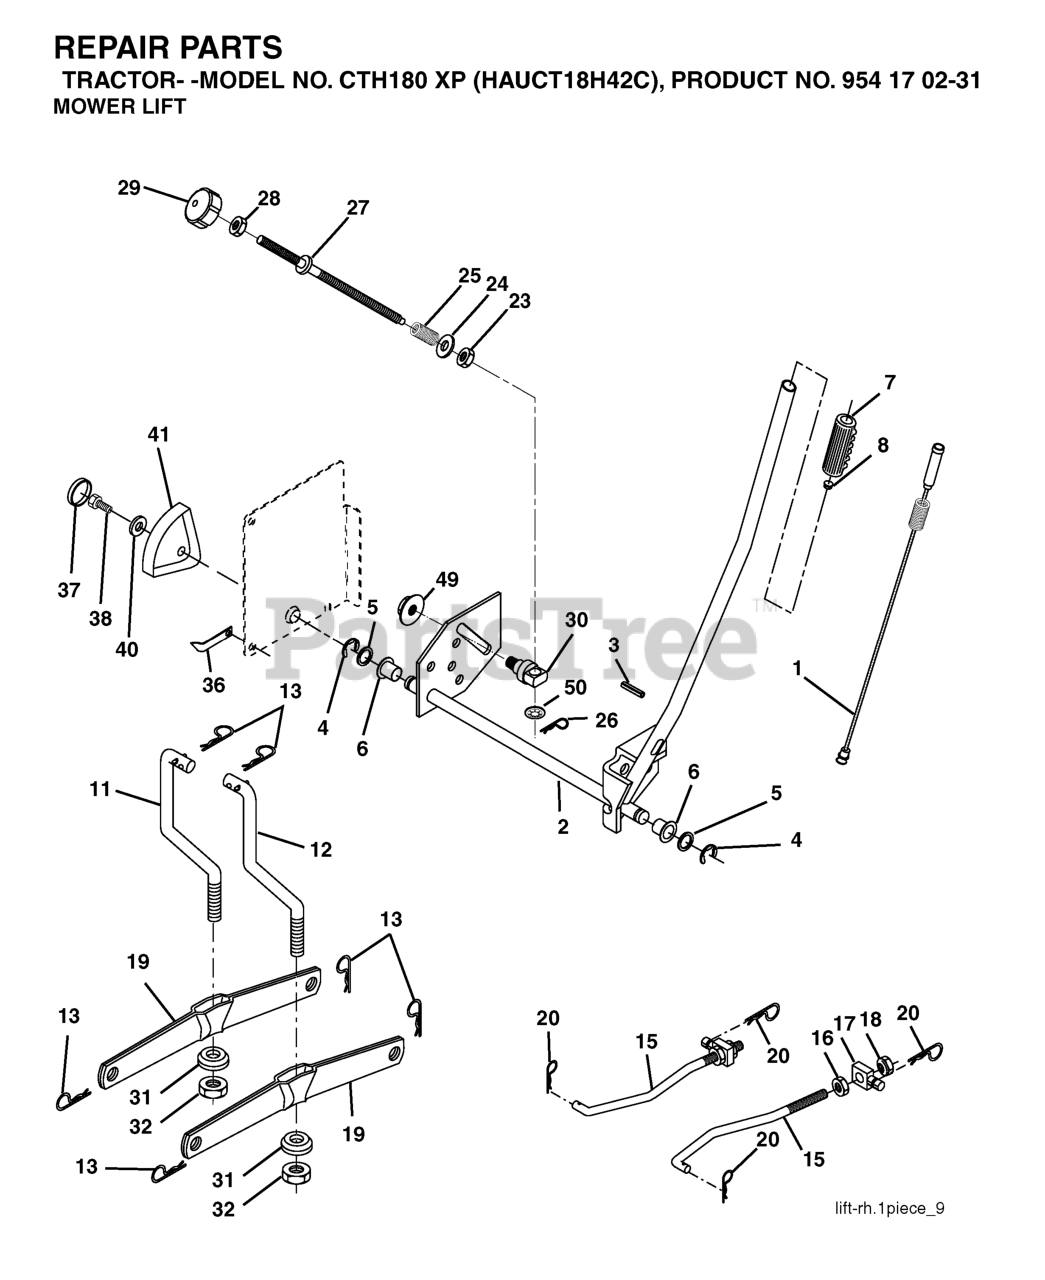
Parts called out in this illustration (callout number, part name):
1	WIRE.ASM.INNER.SP
2	SHAFT.ASM.LIFT.RH.INF
3	PIN GROOVE
4	RETAINING RING LT
6	BEARING.NYLON
7	GRIP HANDLE
8	PLUNGER BUT KIT
11	LINK
12	LINK
13	RETAINER-SPRNG RB
15	LINK.SUSPENSION.FRONT
16	NUT.HEX.JAM.1/2-13
18	NUT.LK.W/WSH.1/2.
19	ARM.REAR.SUSPENSION
20	SPRING RETAINER
25	SPRING.COMP.INF.H
26	RETAINER CLIP
27	ROD.LIFT.ADJUSTABLE
28	NUT
29	KNOB INF 3/8-16
31	BEARING.PIVOT.LIFT
32	NUT CROWNLOCK 3/8-24
36	POINTER, HEIGHT INDICATOR(2 2)
38	SCREW 5/16-18X1
41	HEIGHT INDICATOR
49	NUT
50	NUT PUSH M
